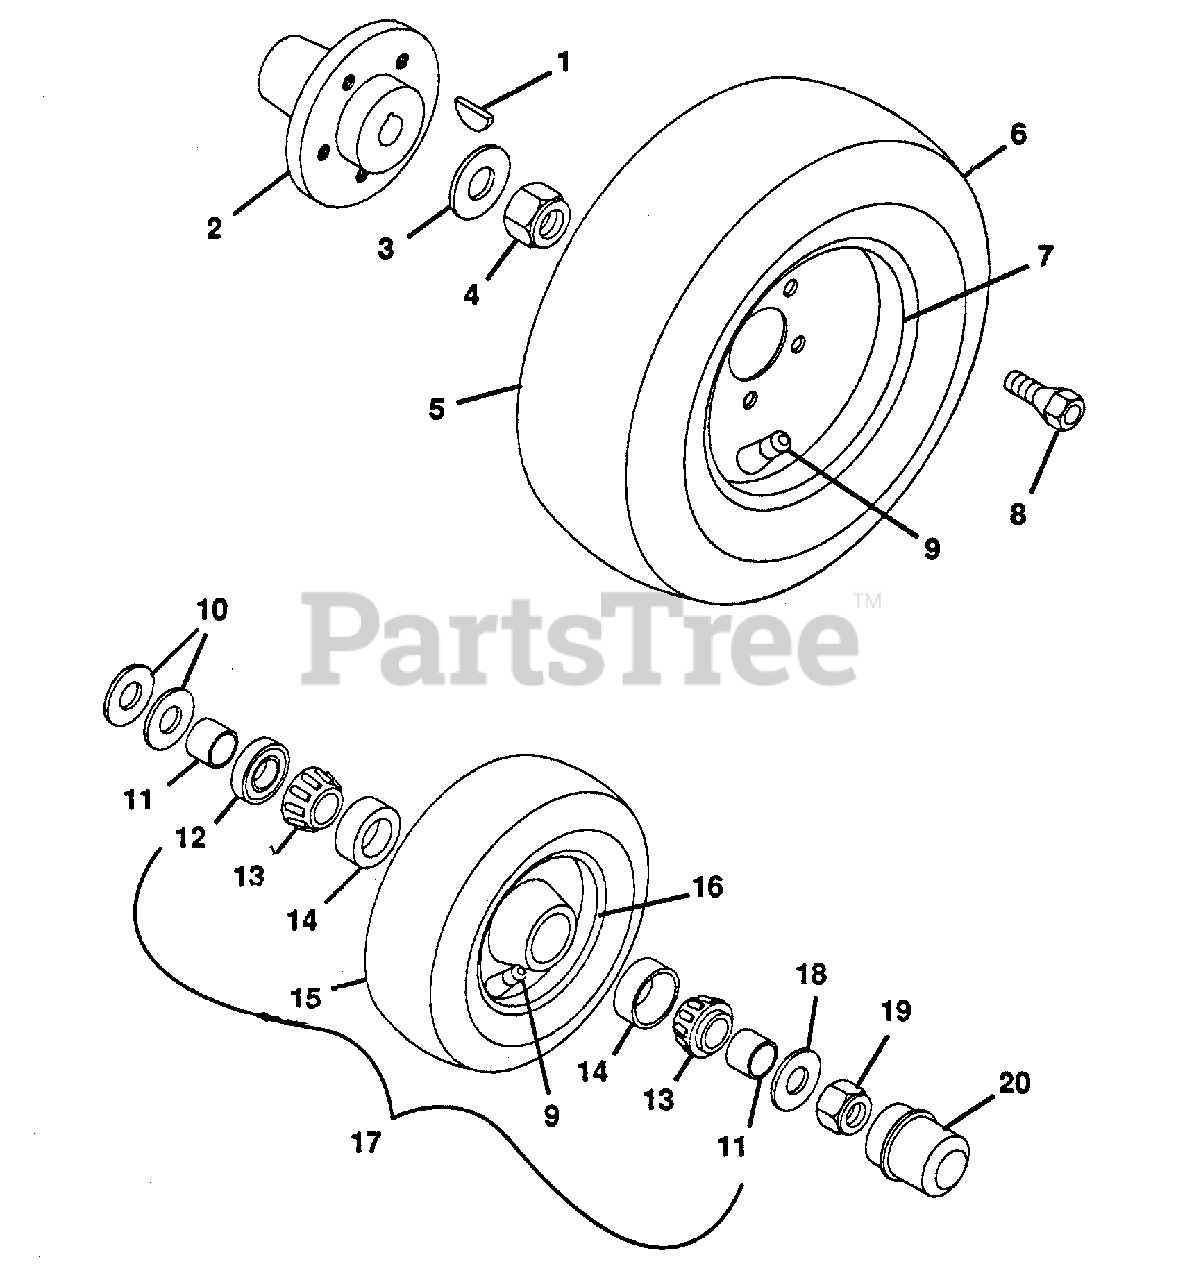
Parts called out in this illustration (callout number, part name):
1	KEY, WOODRUFF .250X2.125 SOFT
2	HUB, TAPERED 4-WHEEL
3	WASHER, FLAT .813X2.0X.148
4	NUT, LOCK 3/4-10
5	ASM, REAR WHEEL 23X8.50-12
5	ASM, WHEEL R.H. 23X8.5-12 SGT
5	ASM, WHEEL L.H. 23X8.5-12 SGT
5	ASM, REAR WHEEL 23X10.50-12
6	TIRE, REAR 23X8.50-12
6	TIRE, SUPER TERRA 23X8.50-12
6	TIRE, REAR 23X10.50-12
7	RIM, WELDMENT
8	BOLT, HUB 7/16-20X.75(SPECIAL)
9	ASSEMBLY, VALVE STEM
10	WASHER, FLAT .813X1.37X.100
11	SPACER
12	SEAL, OIL
13	BEARING, CONE LM 11949
14	BEARING, CUP LM 11910
15	TIRE, FRONT 16X6.50-8
15	TIRE, FRONT 16X7.50-8
16	RIM, FRONT WHEEL ASSEMBLY
17	ASSEMBLY, FRONT WHEEL 16X6.50-8
17	ASSEMBLY, FRONT WHEEL 16X7.50-8
18	WASHER, FLAT .656X1.312X.095
19	NUT, LOCK 5/8-11
20	CAP
